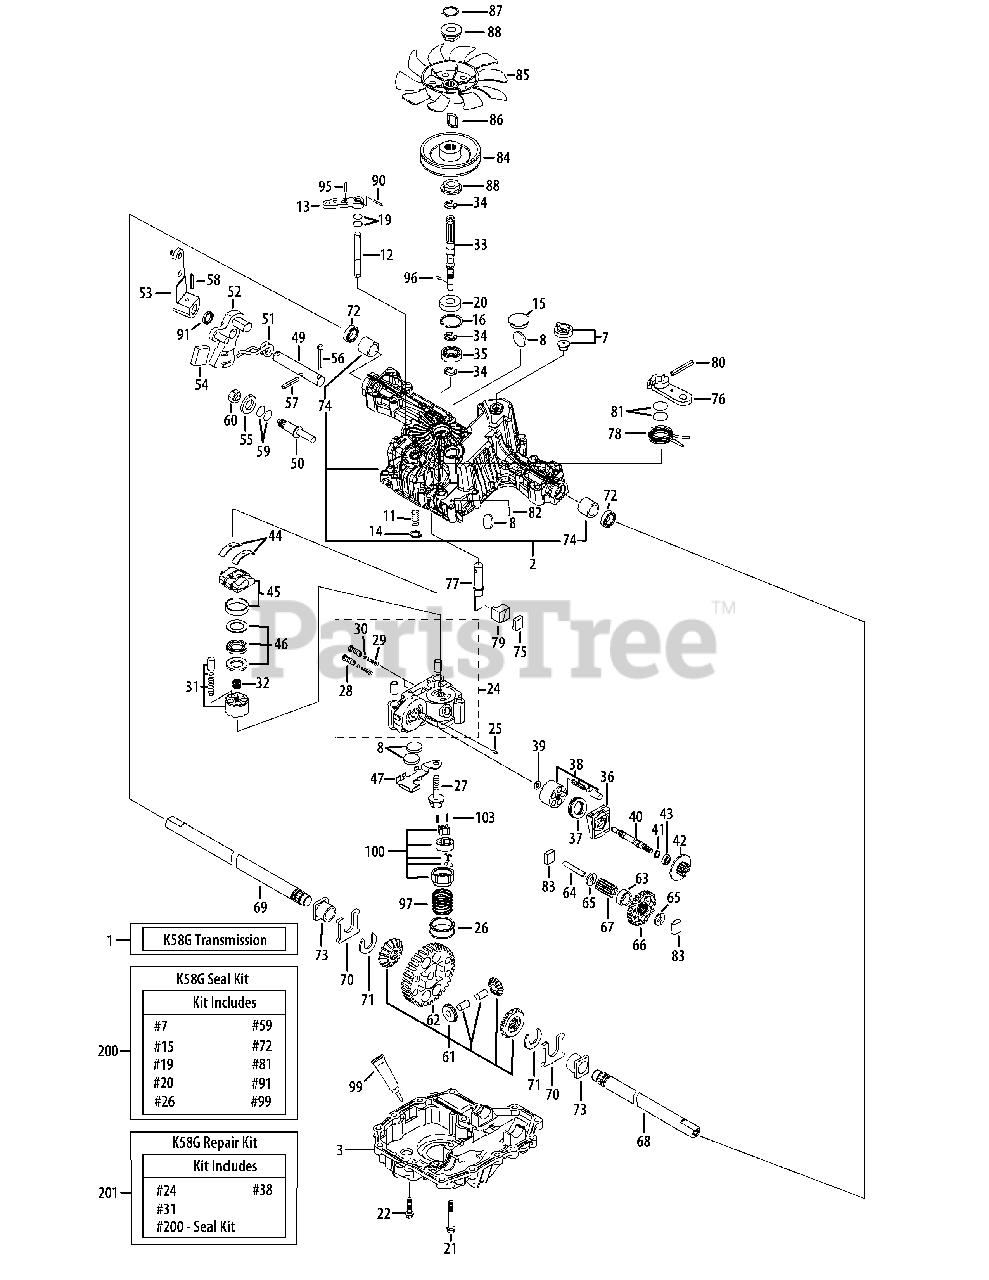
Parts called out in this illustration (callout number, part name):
1	K58G Transaxle
2	Kit, Housing
12	Bypass Shaft A
15	Sealing Cap 30
16	Snap Ring C 35
19	O-Ring 1A P10A
20	Seal TC 153507
21	Tapping Screw 8 x 55
22	Tapping Screw 8 x 30
24	Kit, Center Case
28	IDS Valve 1.2
30	IDS Filter 300
31	Kit, Cylinder Block (Pump)
35	Bearing 6202C3
36	Motor Housing
37	Thrust Ball Bearing
38	Kit, Cylinder Block
39	Washer 12 x 24 x 1
41	Snap Ring S15
44	Thrust, Plastic
45	Swash Plate Clamp
46	Kit, Thrust Bearing (Pump)
47	Magnet Holder
49	Control Shaft
51	Torsion Spring, Standard
52	Control Arm A
53	Control Lever F
56	Cotter Pin 1/8" x 3/4"
57	Spring Pin 6 x 36
58	Roll Pin 6 x 40
61	Diff Gear Kit
64	Reduction Shaft
65	Washer 12 x 32 x 3.2
66	Reduction Gear
68	Axle Shaft, Left
69	Axle Shaft, Right
70	Thrust Washer
72	Seal 25.4 x 42 x 8
78	Brake Return Spring
79	Brake Actuator
80	Spring Pin 5 x 32
81	O-Ring 1A P12
83	Support Bushing
88	Spline Collar
90	Spring Pin 3.0A x 20
91	Oil Seal 16 x 22 x .03
95	Spring Pin 3.0A x 16
96	Pin 2.5 x 9.8
97	Charge Spring
99	Sealant
100	Charge Pump Kit
200	Kit,Seal
201	Repair Kit,
